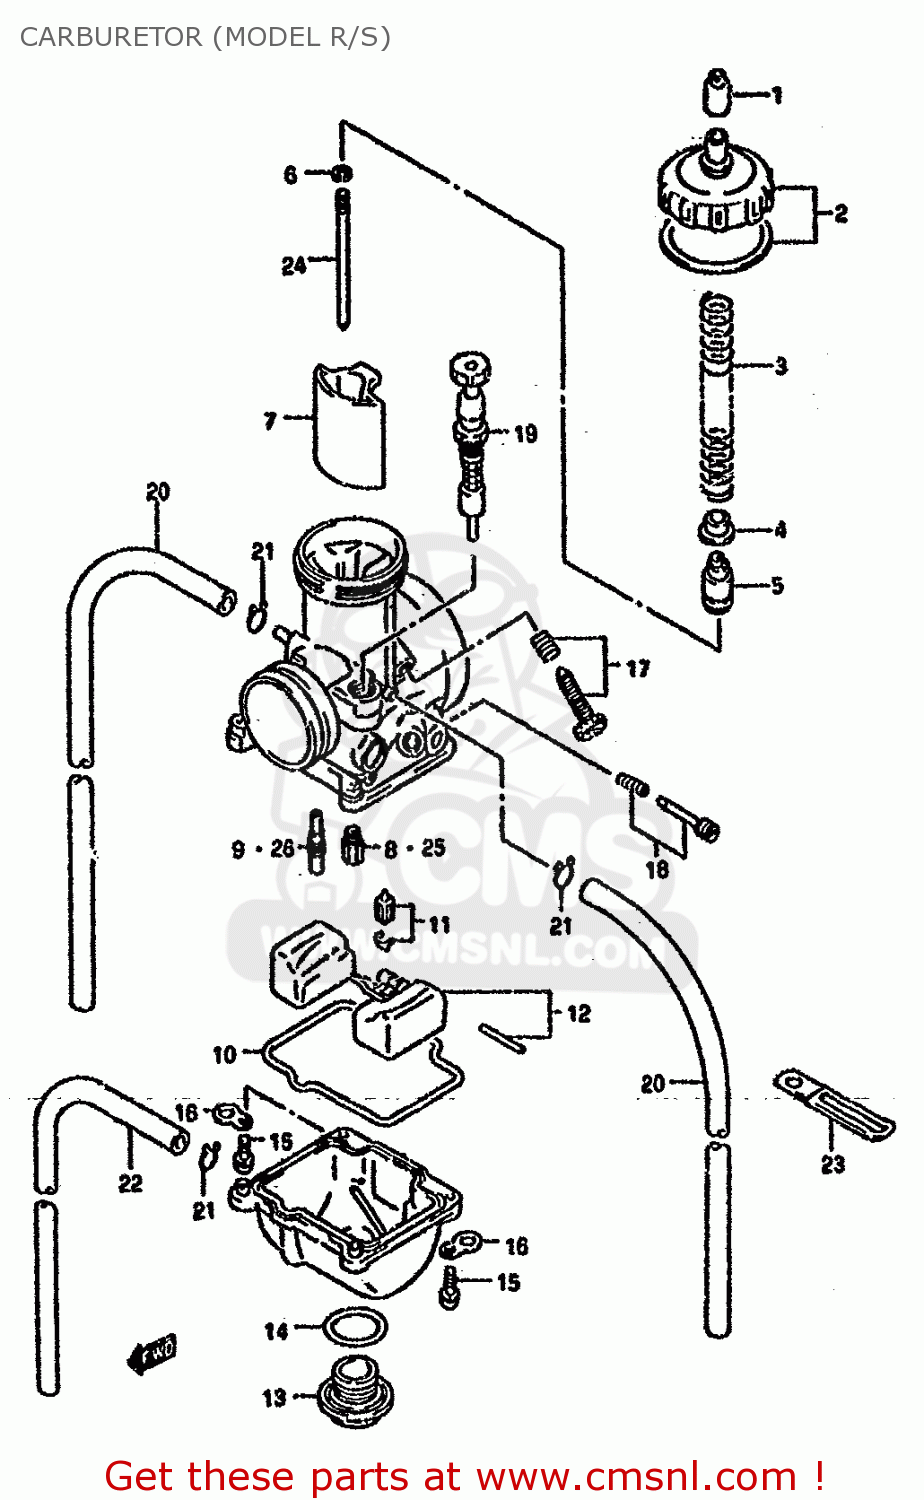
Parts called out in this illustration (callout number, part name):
1	CAP,CARBURETOR
2	CAP SET,TOP
3	SPRING,THROTTLE VALVE
4	COLLAR,THROTTLE VALVE
5	HOLDER,CABLE
6	CLIP,NEEDLE
7	VALVE,THROTTLE
8	JET,MAIN(168)
9	JET,SLOW(50)
10	GASKET,FLOAT CHAMBER
11	VALVE SET,FLOAT
12	FLOAT SET
13	BOLT,DRAIN
14	O RING
15	SCREW
16	PLATE
17	SCREW SET,STOP
18	SCREW SET,AIR
19	STARTER VALVE
20	HOSE (4X7X440)
21	CLIP
22	HOSE(3.5X6.5X600)
23	CLAMP
24	NEEDLE SET,JET
25	JET,MAIN(145)
26	JET,SLOW(35)
